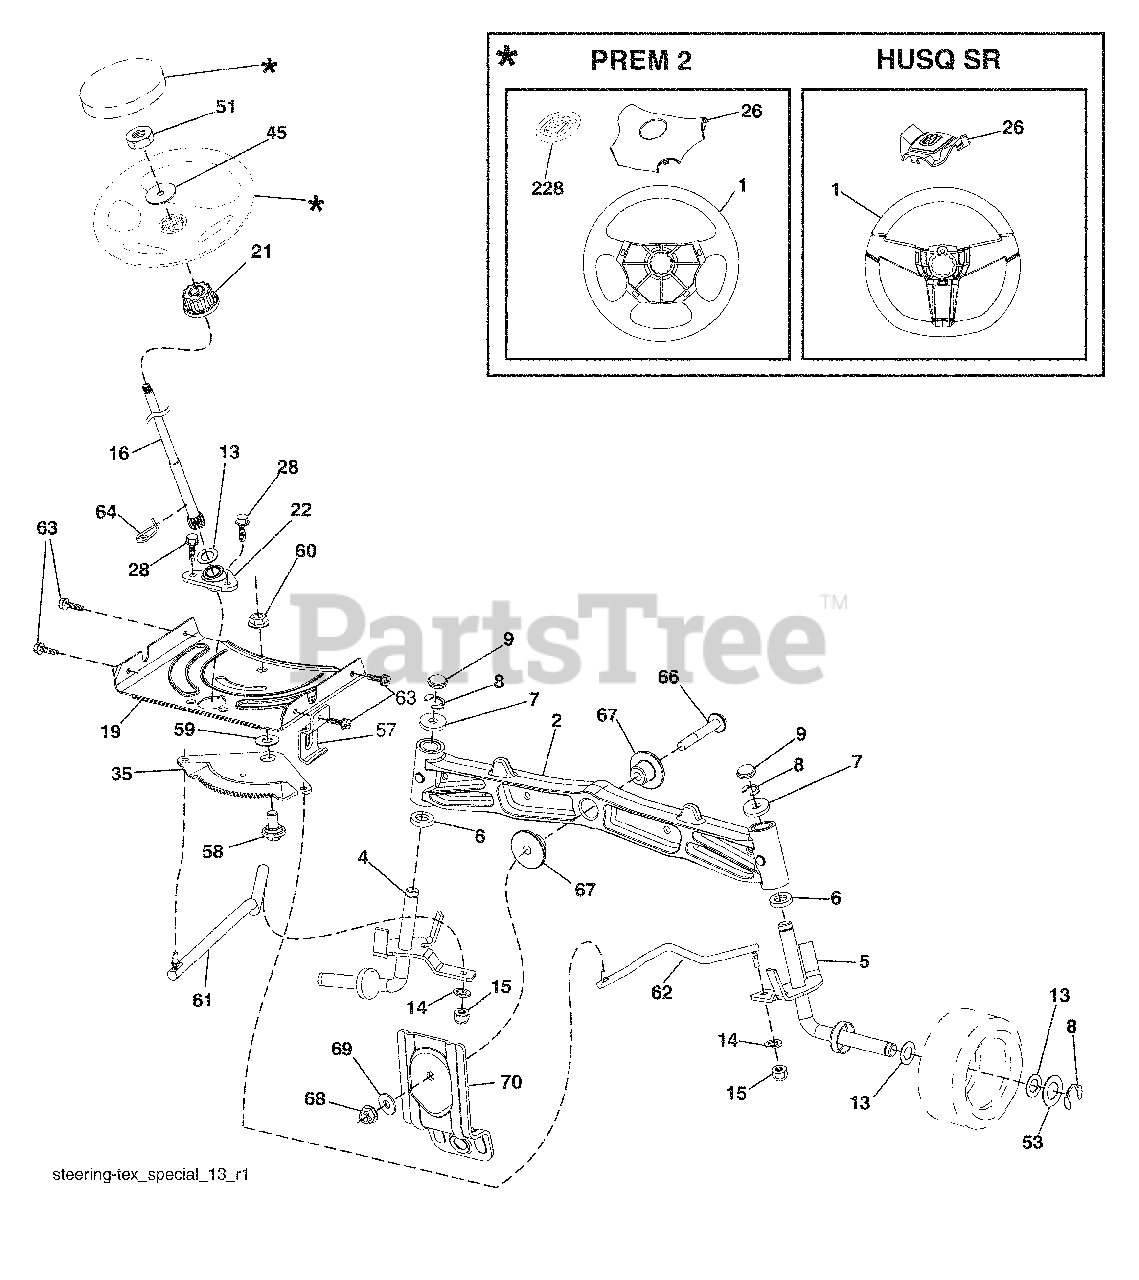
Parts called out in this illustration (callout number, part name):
1	Wheel, Steering
2	Axle Asm., Front
4	Spindle Asm. LH
5	Spindle Asm. RH
6	Bearing, Race Thrust Harden
7	Washer 25/32 x 1-5/8 x 16 Ga.
8	Ring, Clip #T5304-75
9	Cap, Spindle
13	Washer 25/32 x 1-1/4 x 16 Ga.
14	Washer, Lock Hvy Hlcl Spr 3/8
15	Nut, Crown Lock 3/8-24 unf
16	Shaft Steering
19	Plate Steering
21	Adapter, Wheel Steering
22	Bushing, Strg. Blk
26	Insert, Wheel Steering
28	Screw 3/8-16 x 3/4
35	Gear, Sector Plate
45	Washer 9/16 x 2-3/8 x 12 Ga.
51	Nut Hex Jam Toplock 1/2-20 unf
53	Washer Hardened .793 x 1.637 x .060
57	Bracket Upstop
58	Bolt Shoulder Sector Pivot CFM
59	Washer Thrust Sector Steering
60	Nut Flange Lock 5/8-11
61	Draglink, LH
62	Draglink, RH
63	Screw 5/16-18 x 3/4
64	Retainer Clip Spring Steering
66	Bolt Hex Fghd 7/16-14 x 3 Serr
67	Bushing PM Front Axle
68	Nut Lock Flange 7/16-14 Gr. 5
69	Washer 1.5 x .505 x .118
70	Bracket Deck Susp. Front
228	Decal Wheel Steering
